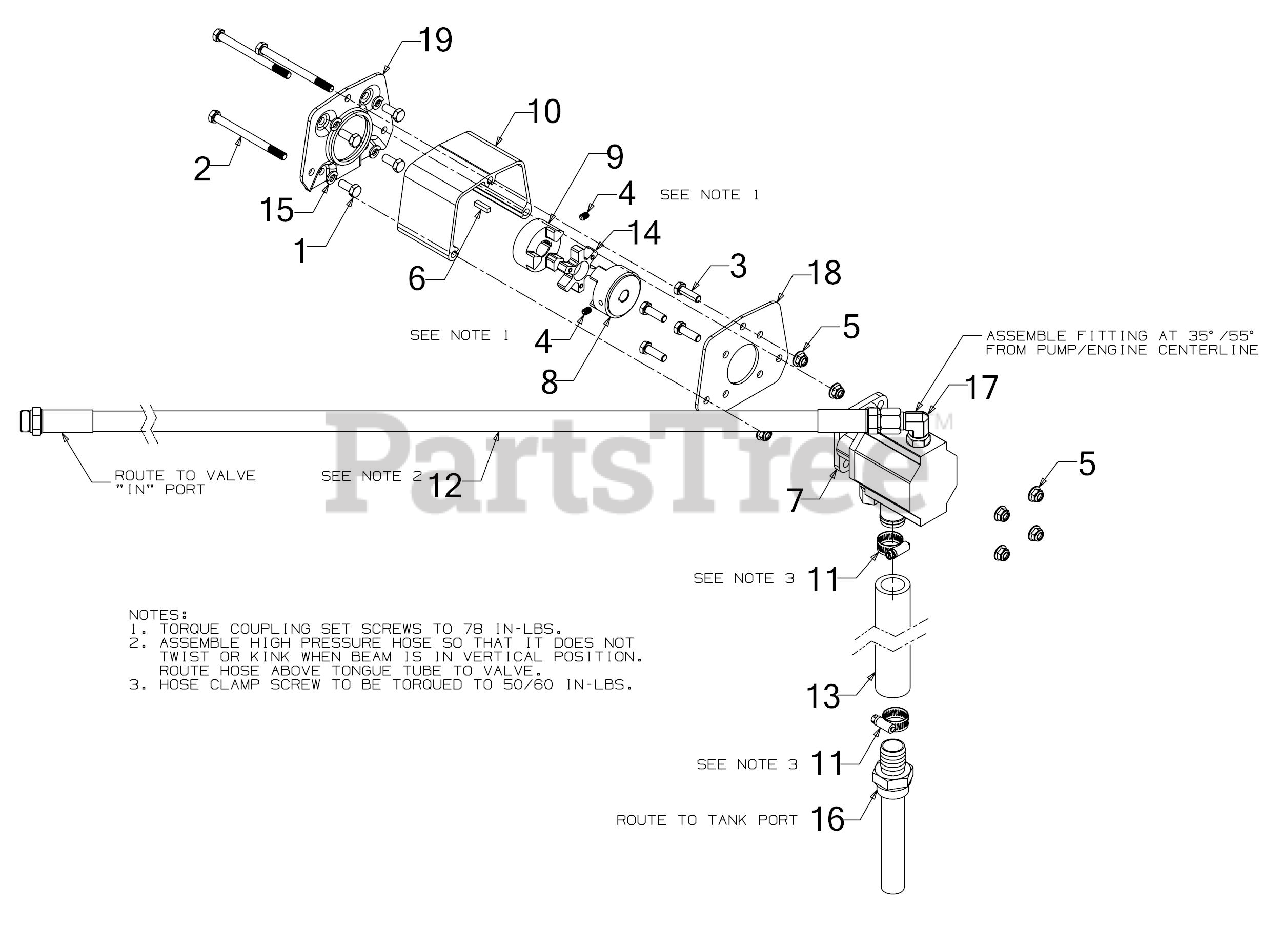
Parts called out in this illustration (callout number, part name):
1	HEX SCREW 5/16-24 x .75
2	HEX SCREW 5/16-18 x 4.00
3	SCREW 5/16-18 x 1.0 GR5
4	SCREW 1/4-20 x .38
5	FLANGE LOCK NUT 5/16-18
6	SQUARE KEY 3/16 x .7
7	LOGSPLITTER GEAR PUMP 11GPM
8	LOGSPLITTER COUPLING .500
9	LOGSPLITTER COUPLING .750
10	COUPLING SHIELD
11	HOSE CLAMP-5/8
12	48" HYDRAULIC HOSE
13	INPUT HOSE
14	SPIDER COUPLING BUSHING
15	LOCK WASHER 5/16
16	INLET FILTER
17	HYDRAULIC FITTING
18	SUPPORT BRACKET
